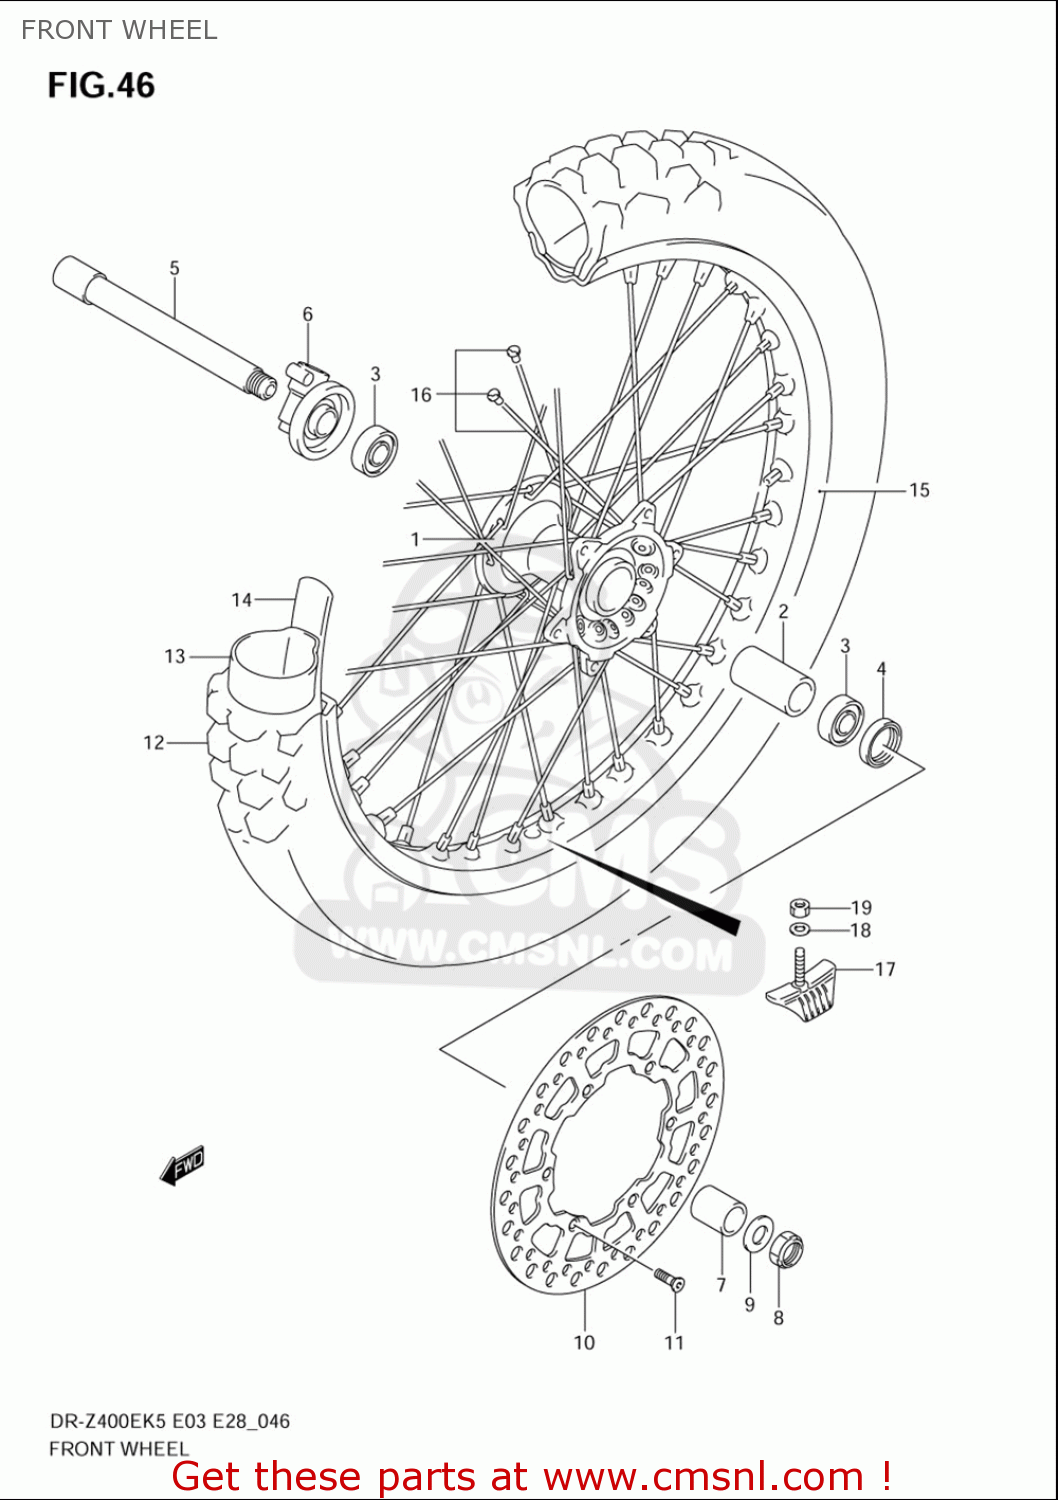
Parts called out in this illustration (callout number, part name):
1	HUB,FR WHEEL
2	SPACER,FR HUB BEARING
3	BEARING
4	SEAL,OIL(25X37X6)
5	AXLE,FR
6	BOX ASSY,SPEEDOMETER GEAR
7	SPACER,FR AXLE,L
8	NUT
9	WASHER(18X26X2.8)
10	DISC,FR BRAKE,L
11	SCREW(6X18)
12	TIRE,FR(80/100-21 51M)
13	TUBE ASSY,WHEEL INNER
14	PROTECTOR,WHL INR TUBE
15	RIM,FR WHEEL(1.60X21 AL)(.WHT)
16	SPOKE SET,FR WHEEL
17	STOPPER,BEAD
18	WASHER
19	NUT
